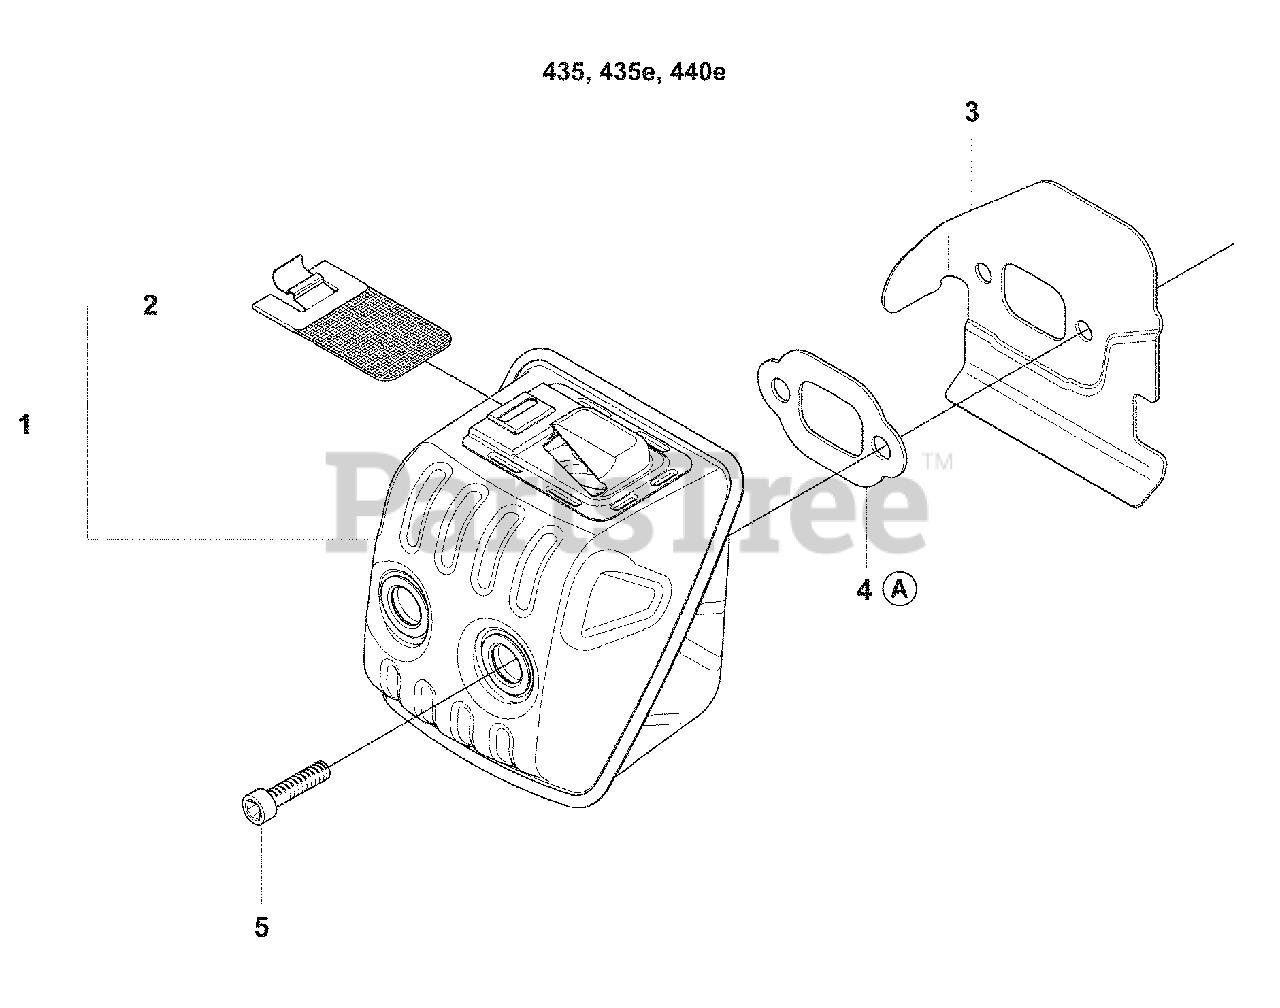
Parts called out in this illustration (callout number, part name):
1	Muffler Assembly
2	Spark Arrester
3	Heat Deflector
4	Gasket
5	Screw, IHSCM
